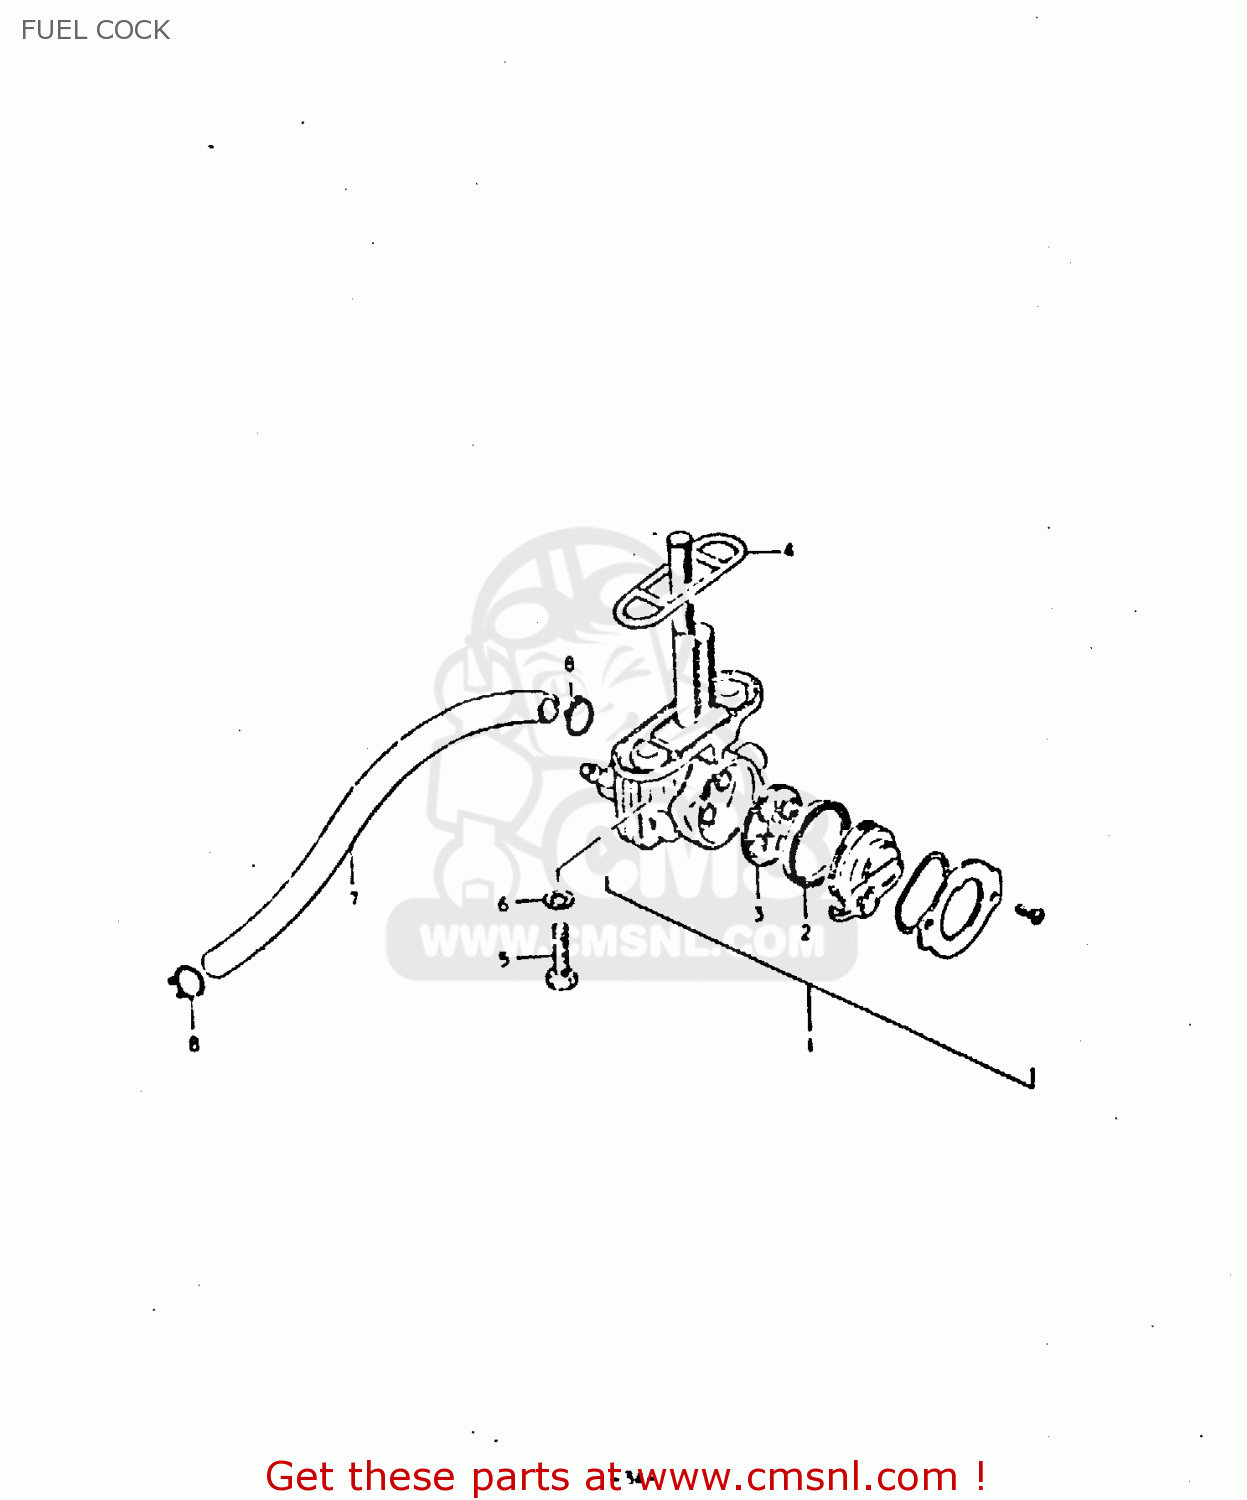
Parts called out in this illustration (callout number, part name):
1	COCK ASSY,FUEL
2	V SEAL,FUEL COCK
3	GASKET (NAS)
4	GASKET, FUEL COCK (NAS)
5	BOLT(6X20)
6	GASKET
7	HOSE
8	CLIP
